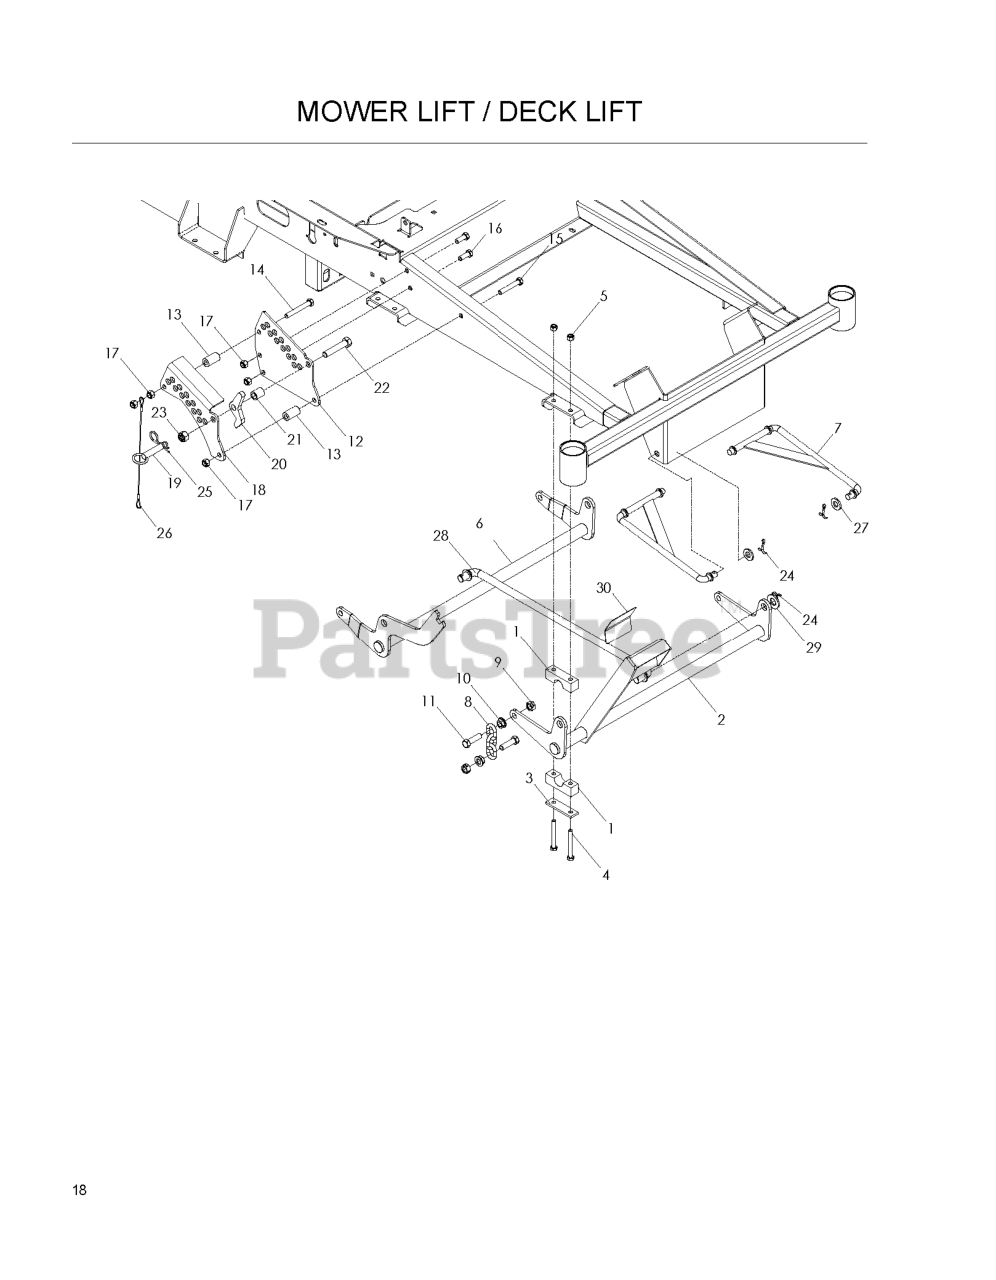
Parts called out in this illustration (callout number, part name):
1	PILLOW BLOCK
2	FRONT LIFT SHAFT
3	REINFORCEMENT BAR
4	HCS 5/16C X 2-3/4
5	NUT 5/16 NYLOC
6	LIFT SHAFT, REAR
7	STRUT LINKAGE
8	LIFT CHAIN - 3 LINK
9	NUT 7/16C CENTERLOCK
10	NUT 7/16C WHIZ
11	HCS 7/16C X 1 1/2
12	HEIGHT ADUST PLATE
13	DECK LIFT SPACER
14	SCREW 3/8C X 2 3/4 HEX CAP
15	HCS 3/8C X 2 1/4
16	HCS 3/8-16X1.GRD.5.ZD
17	NUT 3/8-16 NYLOC
18	HEIGHT ADJUST PLATE, OUTER
20	PAWL, STOP
22	HEX SCREW 1/2-13 X 2.5" GR 5
23	NUT 1/2-13 HEX NYLOC ZD
24	COTTER PIN
25	HAIRPIN #4
27	WASHER 1/2" FLAT
28	CROSS LINK
29	WASHER 5/8 FLAT
30	ANTI-SKID PAD
